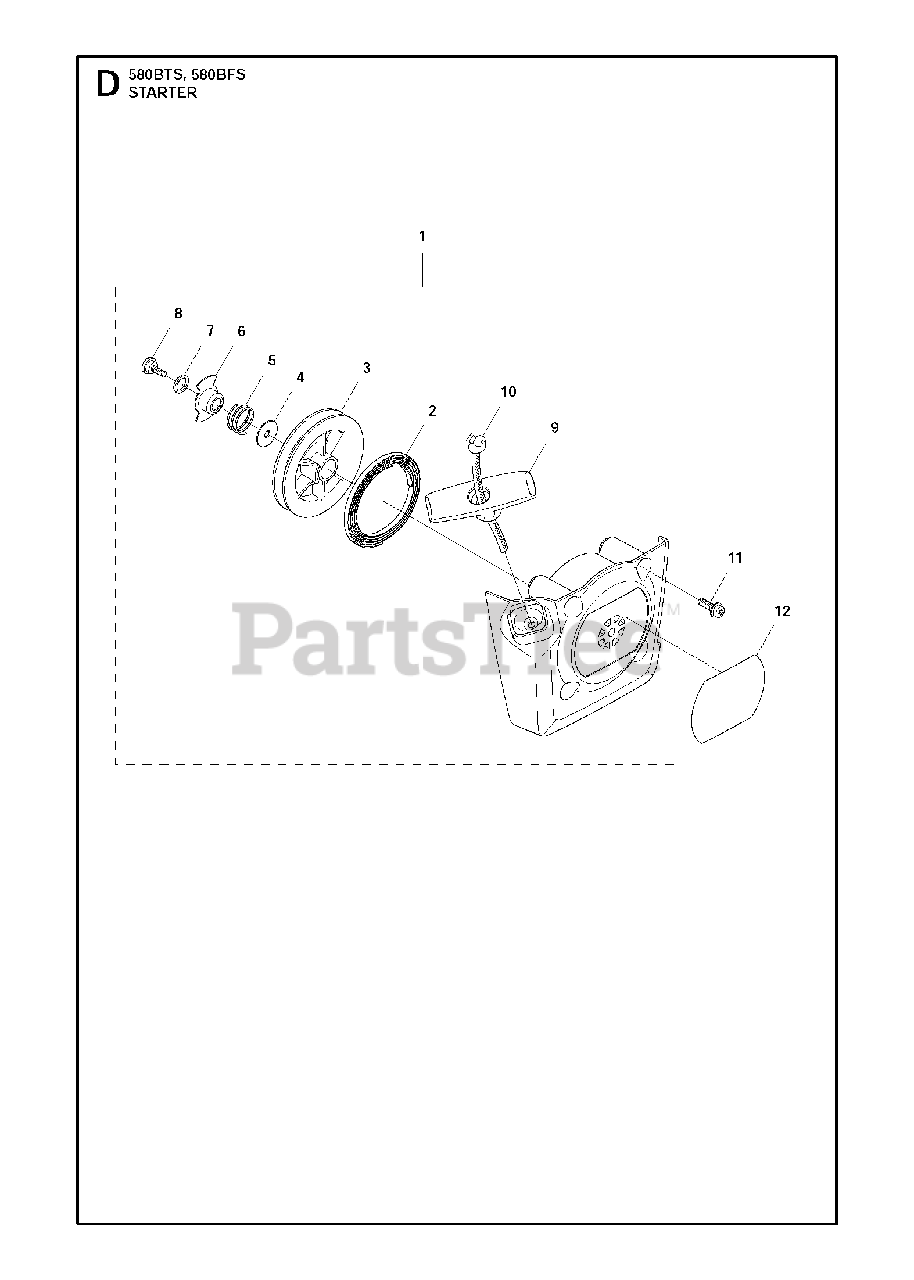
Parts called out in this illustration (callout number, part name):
1	STARTER ASSY
2	SPRING
3	REEL
4	WASHER
5	SPRING FRICTION
6	PLATE
7	WASHER
8	SCREW
9	HANDLE
10	ROPE
12	LABEL RECOIL
12	Recoil Label
